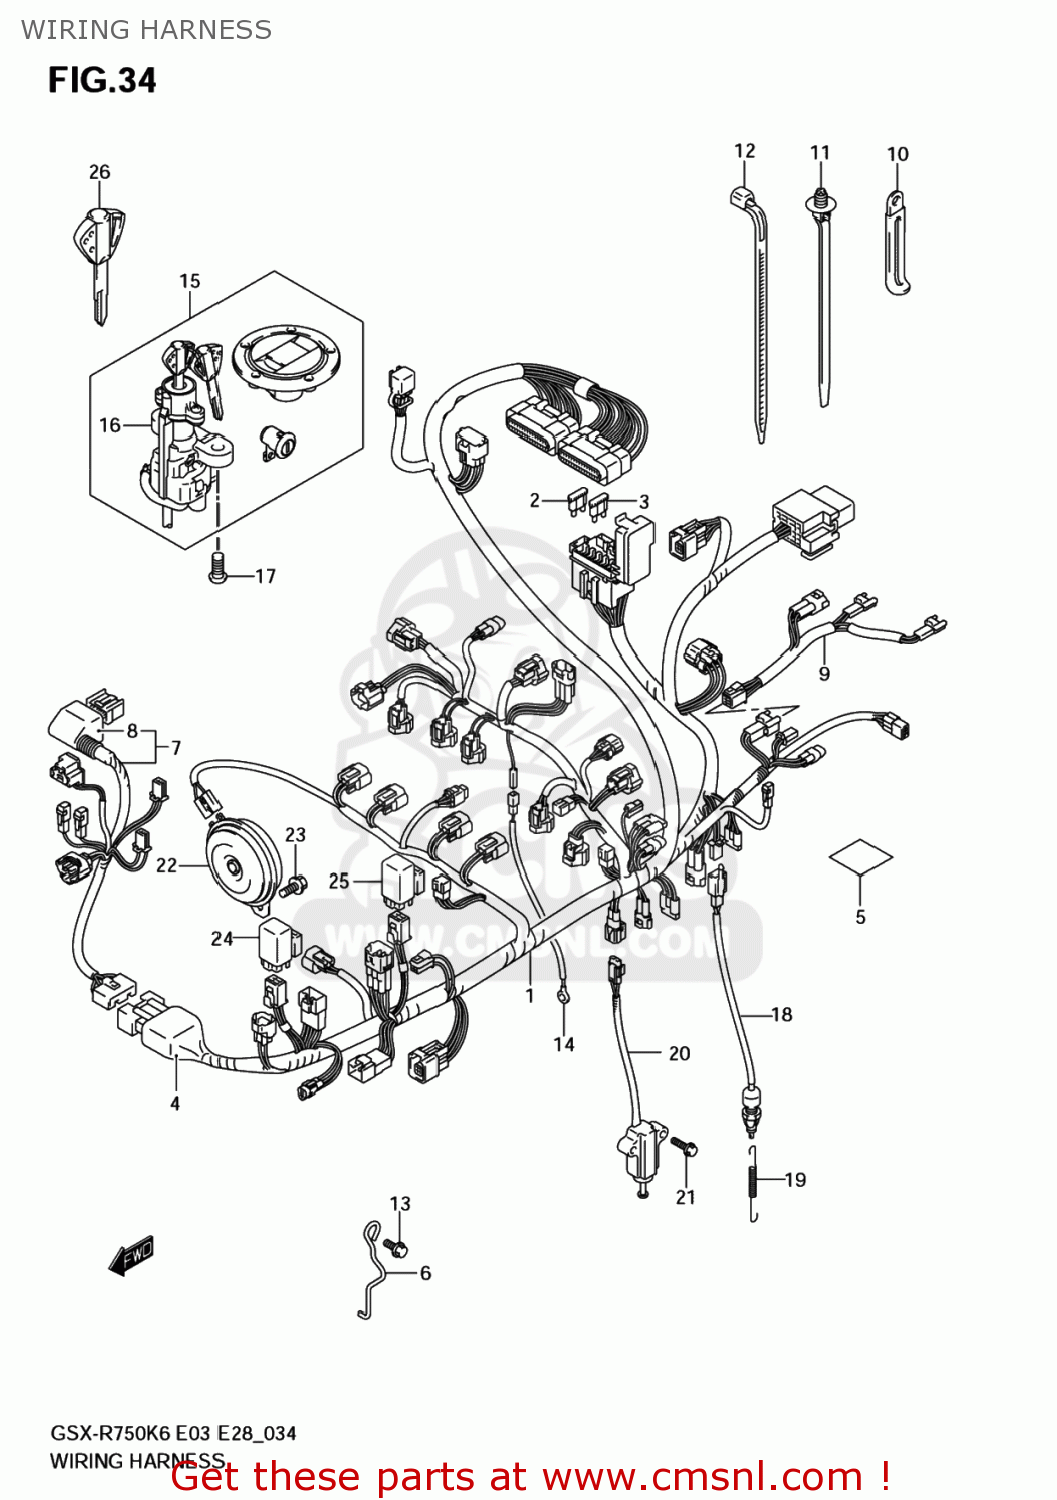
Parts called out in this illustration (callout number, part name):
1	HARNESS,WIRING NO.1
2	FUSE(10A)
3	FUSE(15A)
4	COVER
5	PROTECTOR(30X80X1)
6	GUIDE,WIRING HARNESS
7	HARNESS,WIRING NO.2
8	COVER,CONNECTOR
9	WIRE,RR COMB
10	CLAMP(L:45)
11	CLAMP(L:154)
12	CLAMP(L:125)
13	BOLT
14	WIRE,OIL PRESSURE SWITCH LEAD
15	LOCK SET
16	LOCK ASSY,STEE
17	BOLT(8X20)
18	SWITCH ASSY,STOP LAMP
19	SPRING
20	SWITCH ASSY,SIDE STAND
21	BOLT
22	HORN ASSY
23	BOLT
24	RELAY ASSY
25	RELAY ASSY
26	KEY,BLANK
